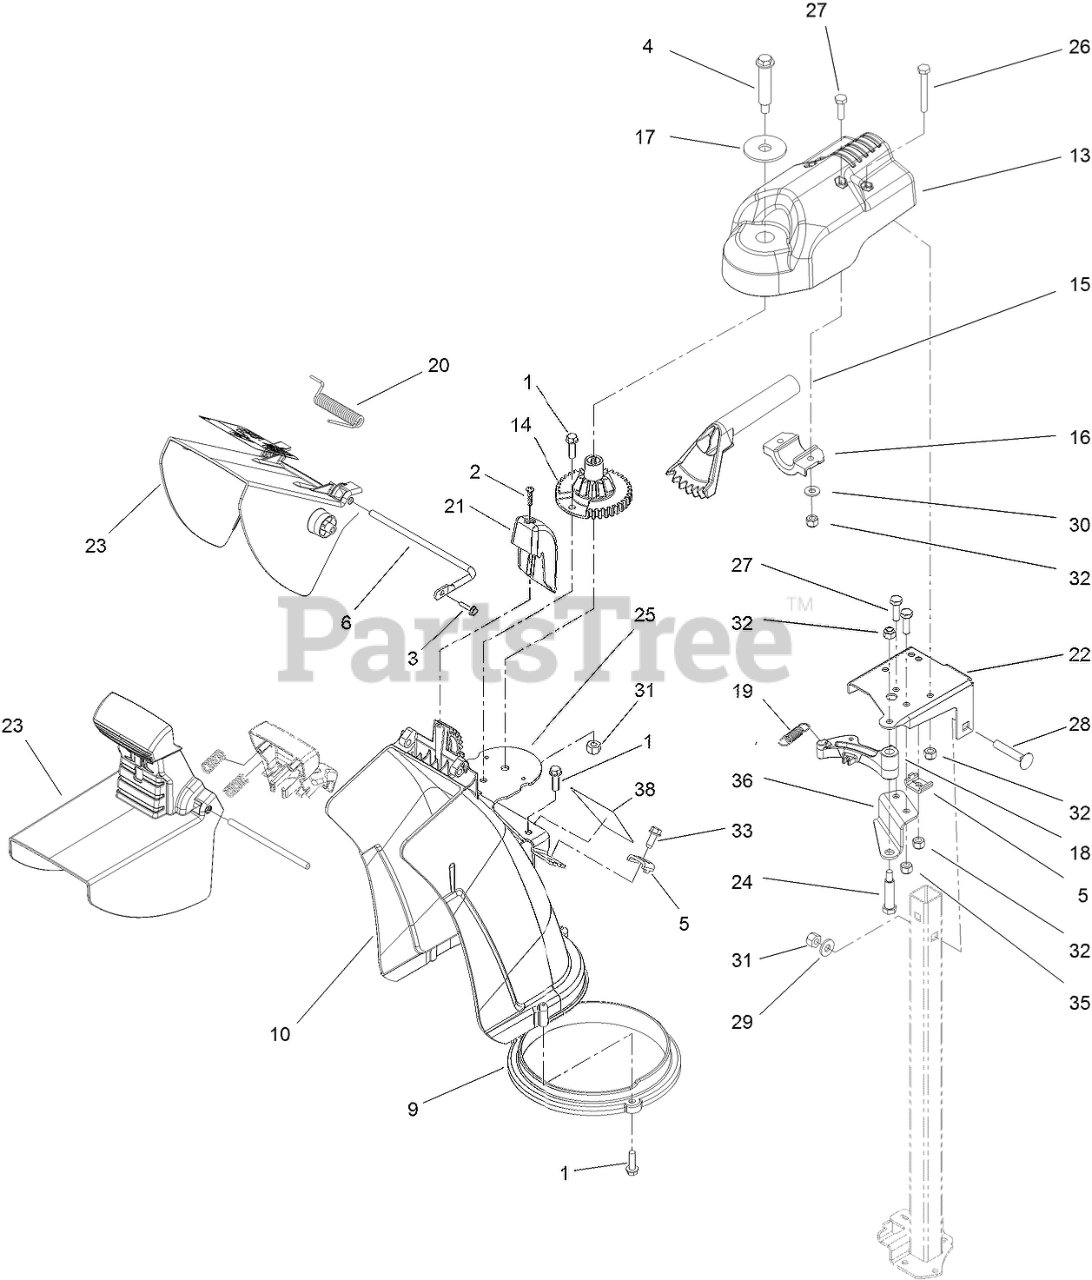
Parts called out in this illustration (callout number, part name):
1	SCREW-HWH
2	SCREW-PPH
3	SCREW-HWH
4	BOLT-SHOULDER
5	CLAMP-CABLE
6	ROD-DEFLECTOR
9	RING-CHUTE
10	CHUTE-DISCHARGE
13	MOUNT-CHUTE, DISCHARGE
14	GEAR-CHUTE
15	GEAR-BEVEL
16	MOUNT-GEAR, BEVEL
17	WASHER-FLAT
18	LATCH-CHUTE
19	SPRING-LATCH, CHUTE
20	SPRING-TORSION
21	CHUTE-COVER
22	BRACKET-SUPPORT, CHUTE
23	DEFLECTOR-CHUTE
24	BOLT-SHOULDER
25	BRACKET-MOUNT, CHUTE
26	SCREW-HH
27	SCREW-HH
28	SCREW-CARR
29	WASHER-FLAT
30	WASHER-FLAT
31	NUT-LOCK, NI
32	NUT-LOCK, NI
33	SCREW-HWH
35	NUT-LOCK, NI
36	BRACKET-SUPPORT, LATCH
38	DECAL-GUARANTEE
